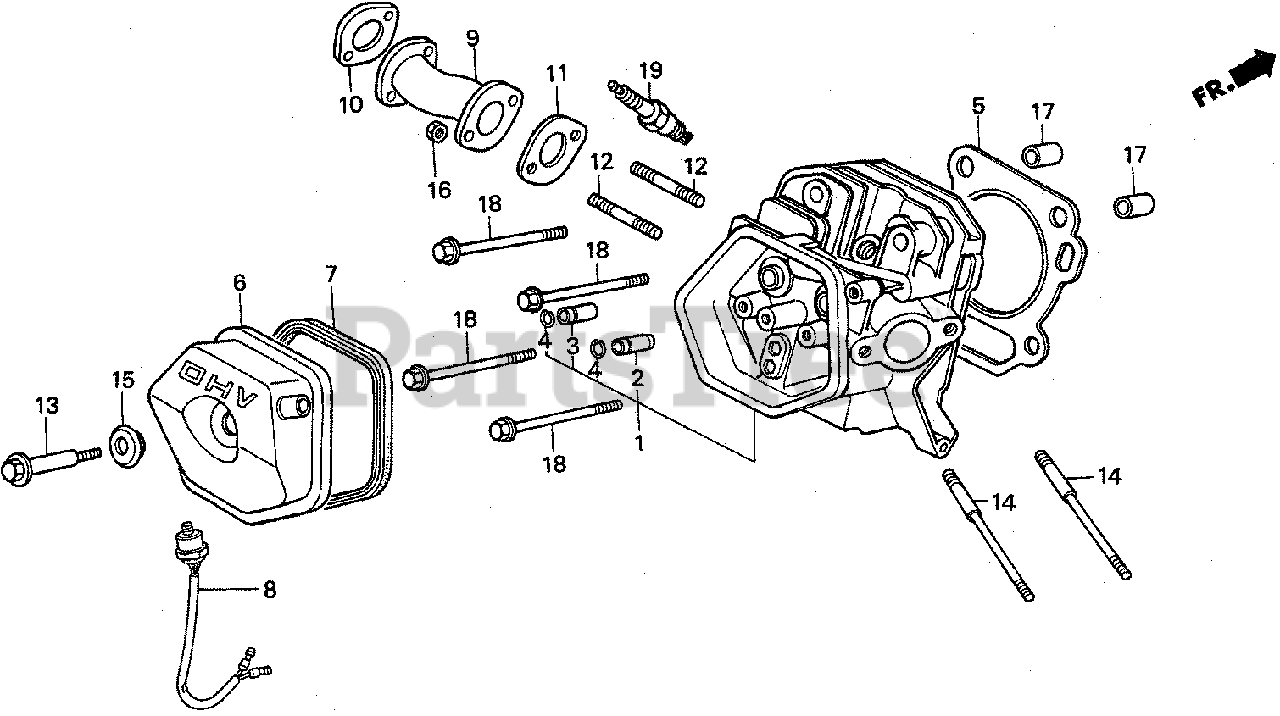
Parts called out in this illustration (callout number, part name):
1	CYLINDER HEAD
2	GUIDE, VALVE (OS)
3	GUIDE, EX. VALVE (OS)
4	CLIP, VALVE GUIDE
5	GASKET, CYLINDER HEAD
6	COVER KIT, HEAD
7	GASKET, CYLINDER HEAD COVER
7	WASHER, DRAIN PLUG (12MM)
8	SWITCH, THERMO
10	GASKET, EX. PIPE
11	GASKET, EX. PIPE
11	GASKET, EX. PIPE (WACKER)
12	BOLT, STUD (8X34)
13	BOLT, HEAD COVER
14	BOLT, STUD (8X111)
15	GROMMET, WIRE
15	WASHER, HEAD COVER
16	NUT, HEX. (8MM)
17	PIN A, DOWEL (12X20)
18	BOLT, FLANGE (10X80)
19	SPARK PLUG (BPR5ES-11) (NGK)
19	SPARK PLUG (W16EPR-U11) (DENSO)
19	SPARK PLUG (BPR5ES) (NGK)
19	SPARK PLUG (W16EPR-U) (DENSO)
